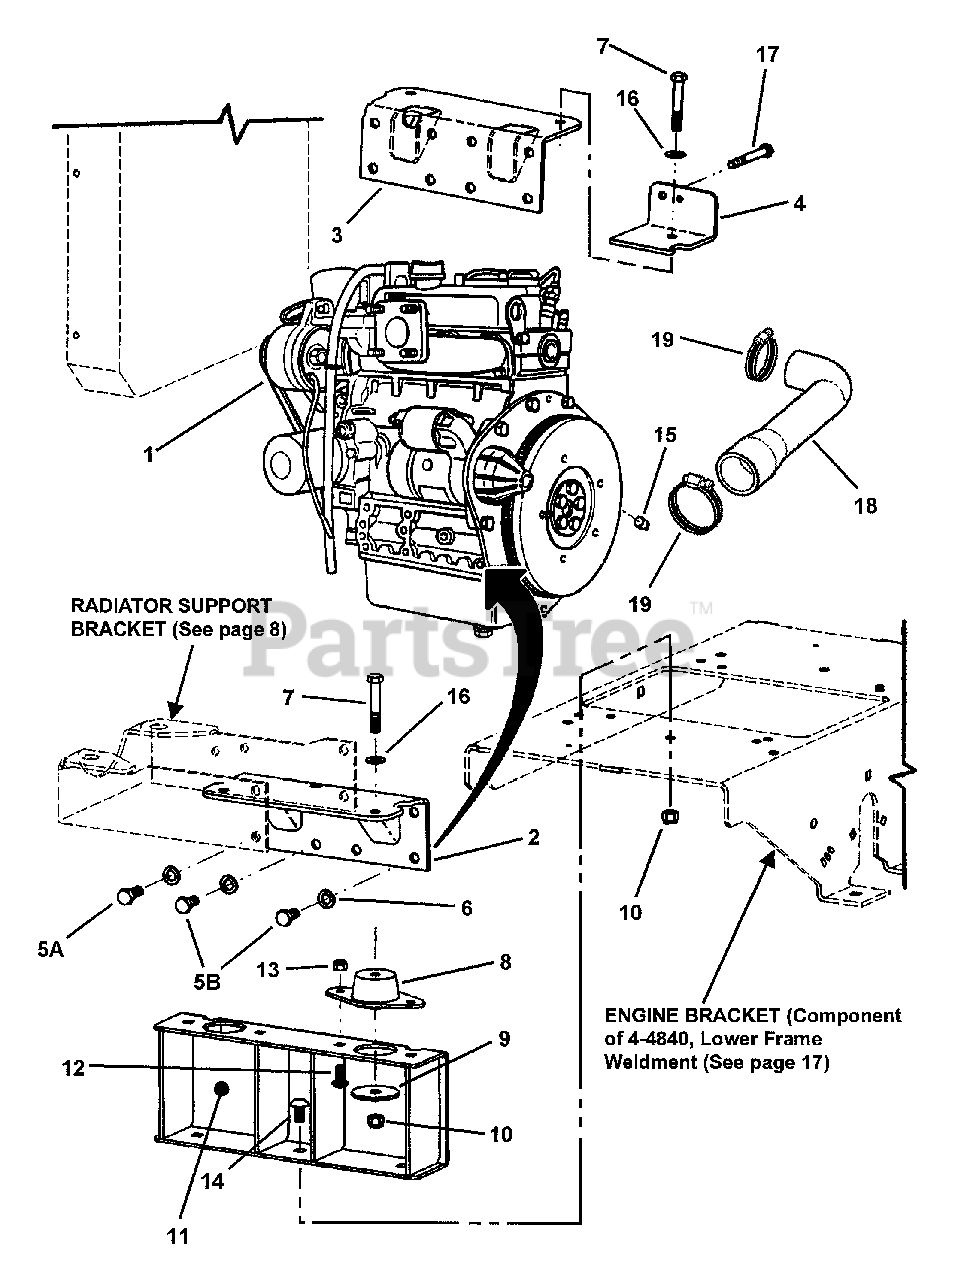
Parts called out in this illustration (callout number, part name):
1	ENGINE, 21 HP Kubota Diesel
2	MOUNT, Engine, Left Hand
3	MOUNT, Engine, Right Hand
4	BRACKET, Fuel Filter
5A	SCREW, M10-1.25 x 25mm Hex Head Cap
5B	SCREW, M10-1.25 x 20mm Hex Head Cap
6	WASHER, 7/16" Split Lock
7	BOLT, 3/8-16 X 2-1/2" GD5 CZ
8	MOUNT, Isolator
9	WASHER, Snubbing
10	NUT, 3/8-16 HEX NYLON LOCK
11	SUPPORT, Lower Channel
12	BOLT, 5/16-18 x 3/4" Short Neck Carriage, Grade 5
13	NUT, 5/16-18 HEX NYLON LOCK
14	BOLT, 3/8-16 x 1-1/4" Short Neck Carriage, Grade 5
15	PLUG, 1/4 Pipe
16	WASHER, 3/8" Flat
17	SCREW, 5/16-18 x 2-3/4" Hex Head Cap, Grade 5
18	HOSE, Air Intake, 23HP Kubota Gasoline
19	CLAMP, 2"
